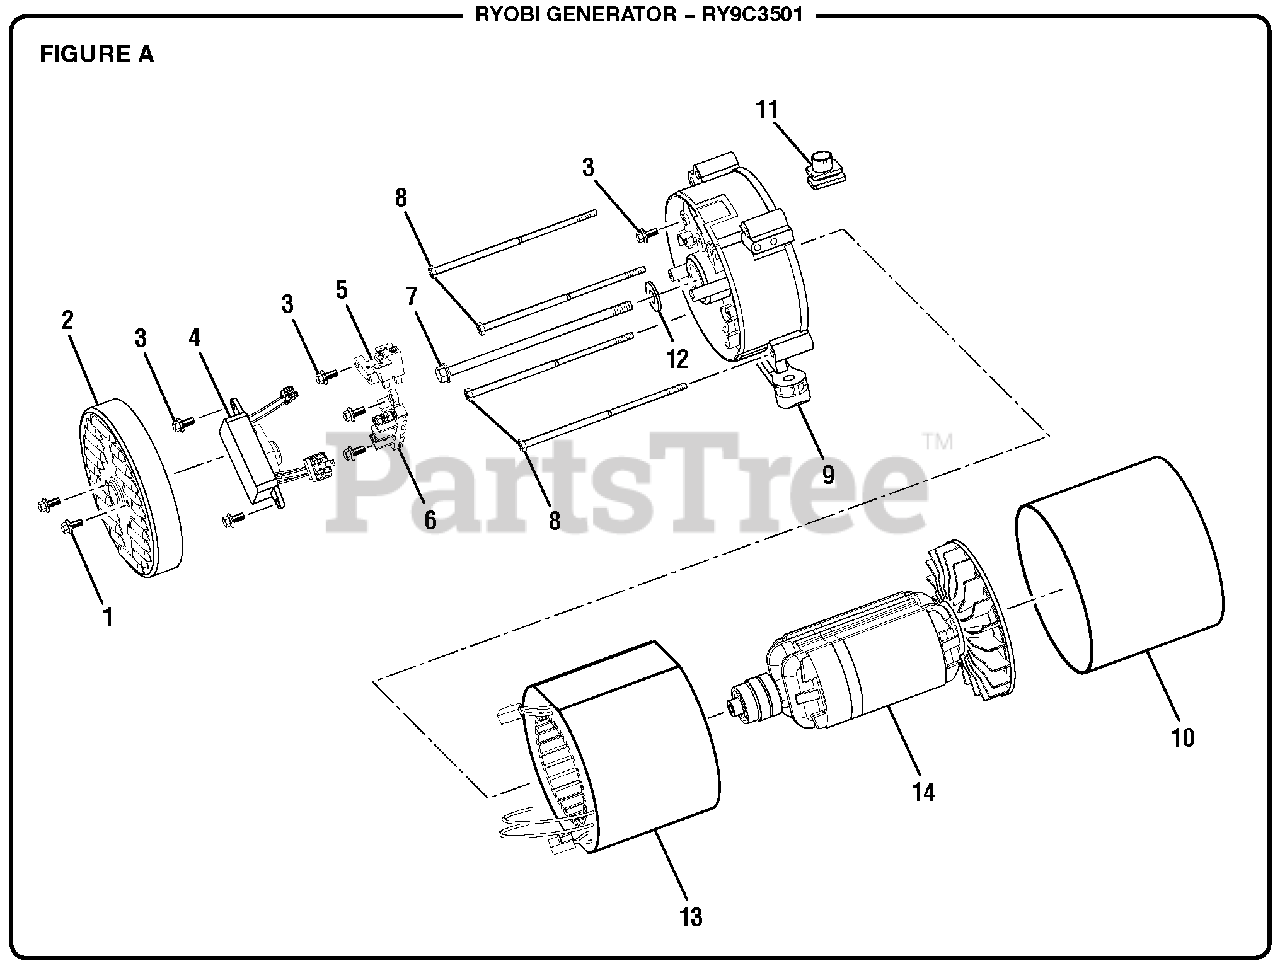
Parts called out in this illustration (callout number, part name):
1	Bolt (M5 x 10 mm)
2	Brush Cover
3	Bolt (M5 x 16 mm, Hex Hd.)
4	Automatic Voltage Regulator
5	Brush Assembly
6	Terminal Block
7	Rotor Bolt
8	Stator Bolt
9	Bearing Housing
10	Generator Head Cover
11	Rubber Boot
12	Rotor Washer
13	Stator Assembly
14	Rotor Assembly
